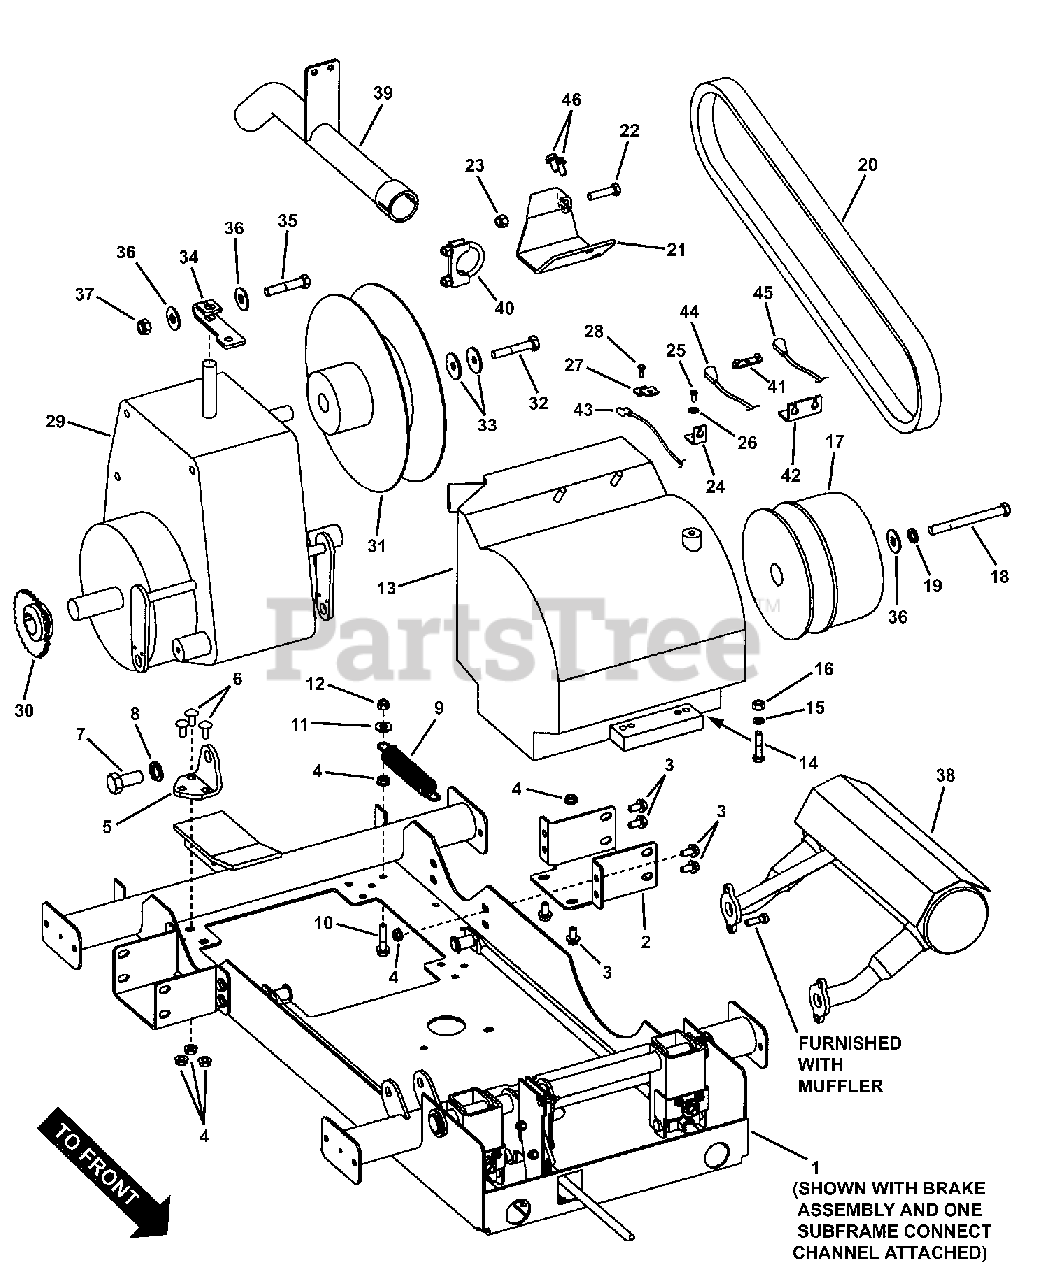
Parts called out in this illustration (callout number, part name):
1	DRIVE BASE ASSEMBLY
2	CHANNEL, Subframe Connect
3	BOLT, Hex Flange Lock, 5/16-18 x 5/8 GR 5
4	NUT, Hex Flange Lock, 5/16-18 GR 5
5	BRACKET, Transmission Mount w/Sq. Holes
6	CARRIAGE BOLT, 5/16-18 x 3/4 GR 5
7	CAPSCREW, Hex Head, M16 x 2 x 35MM
8	WASHER, 16MM Split Lock
9	SPRING, Brake Return
10	BOLT, Hex Flange Lock, 5/16-18 x 1-1/2 GR 5
11	WASHER, .375 x .875 x .083 Flat
12	NUT, Hex Nyloc, 5/16-18
13	* ENGINE, Briggs & Stratton 16HP Vanguard
13	* ENGINE, Briggs & Stratton 16HP w/Generator
14	CAPSCREW, Hex Head, 5/16-24 x 1-1/2 GR 5
15	WASHER, 5/16 Split Lock
16	NUT, Hex, 5/16-24 GR 5 or B
17	CLUTCH, CVT Drive
18	CAPSCREW, Hex Head, 7/16-20 x 4-1/2 GR 5
19	WASHER, 7/16 Split Lock
20	BELT, CVT (Cogged; 58.15 effective length)
21	TORQUE BRACKET, Utility Vehicle
22	CAPSCREW, Hex Washer Head, 3/8-16 x 1-1/2 GR 5
23	NUT, Hex Nyloc, 3/8-16
24	ANCHOR, Throttle
25	SCREW, Pan Head, Phillips, #10-32 x 1/2
26	WASHER, #10 External Tooth Lock
27	THROTTLE PLATE, B&S Vanguard
28	SCREW, Hex Head Shoulder, #10-32 x 1/2
29	TRANSAXLE, Turf Torq KT35C
30	SPROCKET, # 35-3/8 Pitch
31	PULLEY, CVT Drive
32	CAPSCREW, Hex Head, M10-1.5 x 60 (w/nyloc patch)
33	WASHER, Cone
34	SHIFT ARM, CVT
35	CAPSCREW, Hex Head, 7/16-20 x 2-1/4 GR 5
36	WASHER, 7/16 Flat (Type A, Wide)
37	NUT, Hex Top Lock, 7/16-20
38	MUFFLER, 16 HP B&S Vanguard
39	TAILPIPE, UV-2
40	MUFFLER CLAMP, 1-5/8
41	THROTTLE LINK, B&S Vanguard
42	BRACKET, Throttle Adjustment
43	CABLE, Throttle, 16 HP Vanguard
44	CABLE, Throttle, Pedal, Powerlink
45	THROTTLE, Remote, Powerlink
46	CAPSCREW, Hex Head, M8-1.25 x 16
